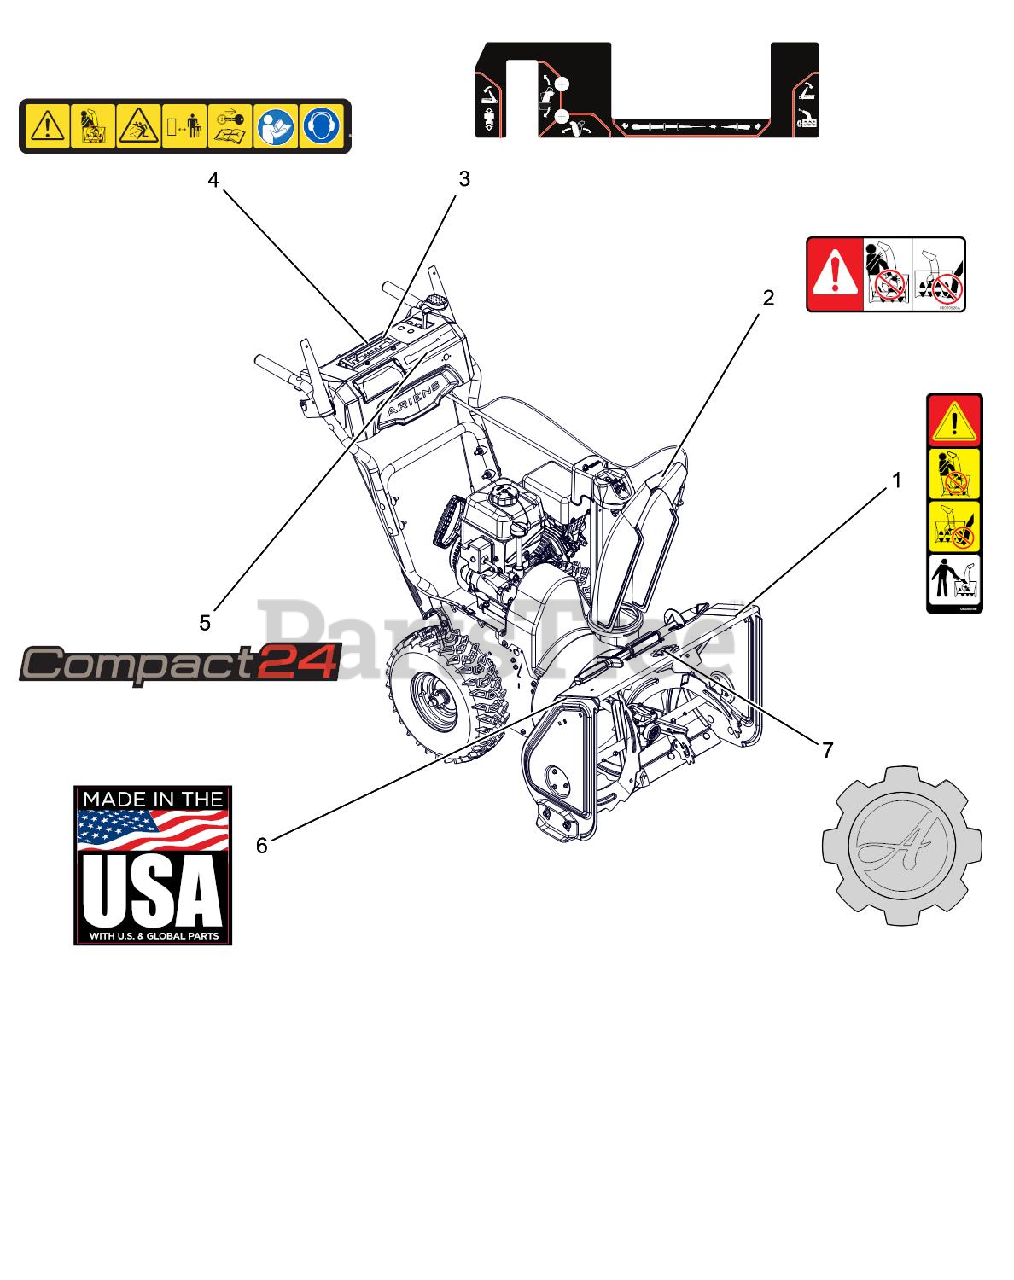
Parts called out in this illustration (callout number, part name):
1	DECAL, DANGER - ROTATING PARTS
2	DECAL, DANGER
3	DECAL,CONTROL-COMP REMOTE
4	DECAL,DASH - SAFETY
5	DECAL, DASH - COMPACT 24
6	DECAL, MADE IN USA
7	DECAL, ARIENS-GEAR BADGE
